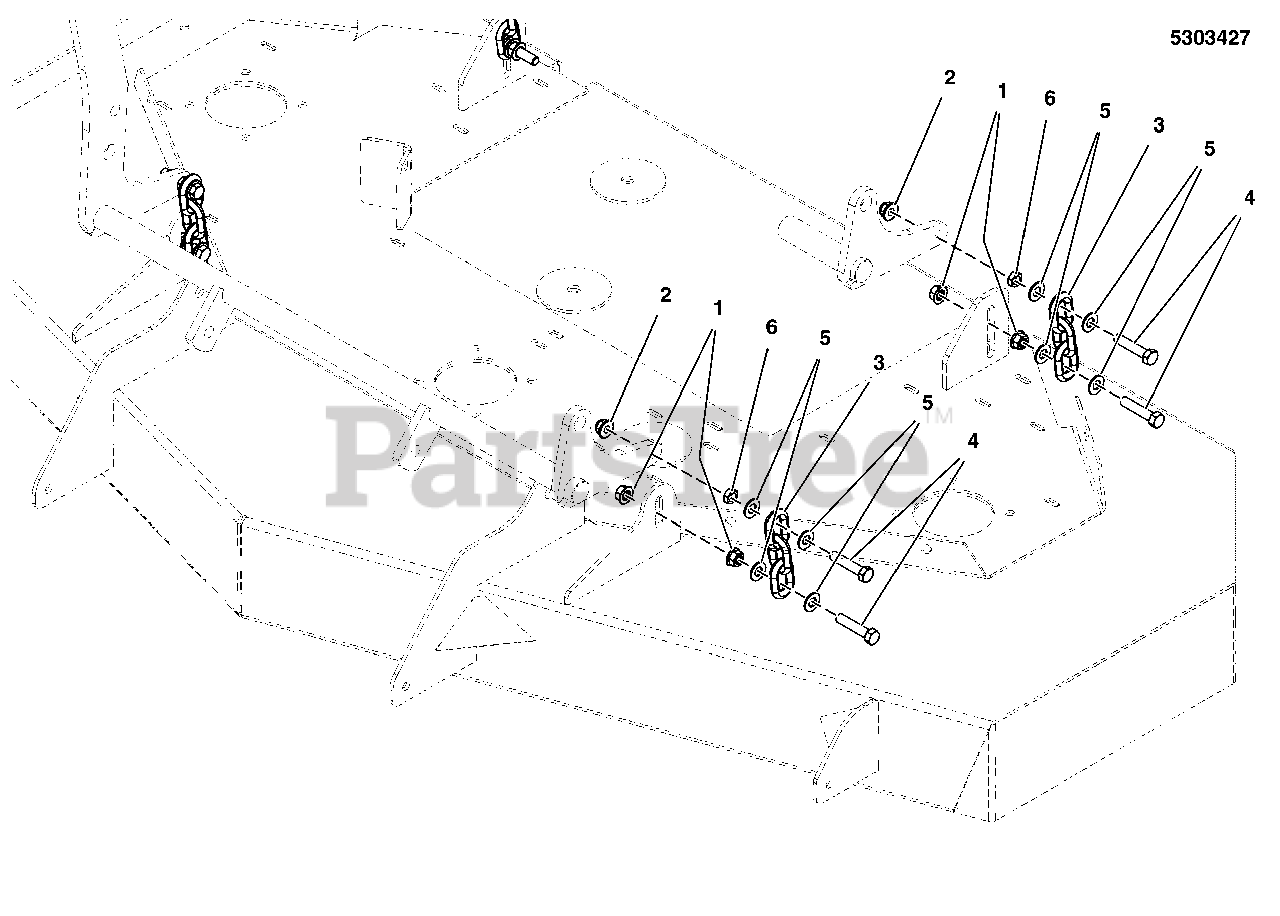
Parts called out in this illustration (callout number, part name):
1	NUT, 3/8-16 HEX SERRATED FLANGE
2	NUT, Hex Flange, Nylock, 3/8-16
3	CHAIN, 5/16 GD30, 3 LINKS
4	BOLT, 3/8-16 X 1-3/4 GD5
5	WASHER, 3/8 SAE
6	NUT, 3/8-16 HEX JAM
